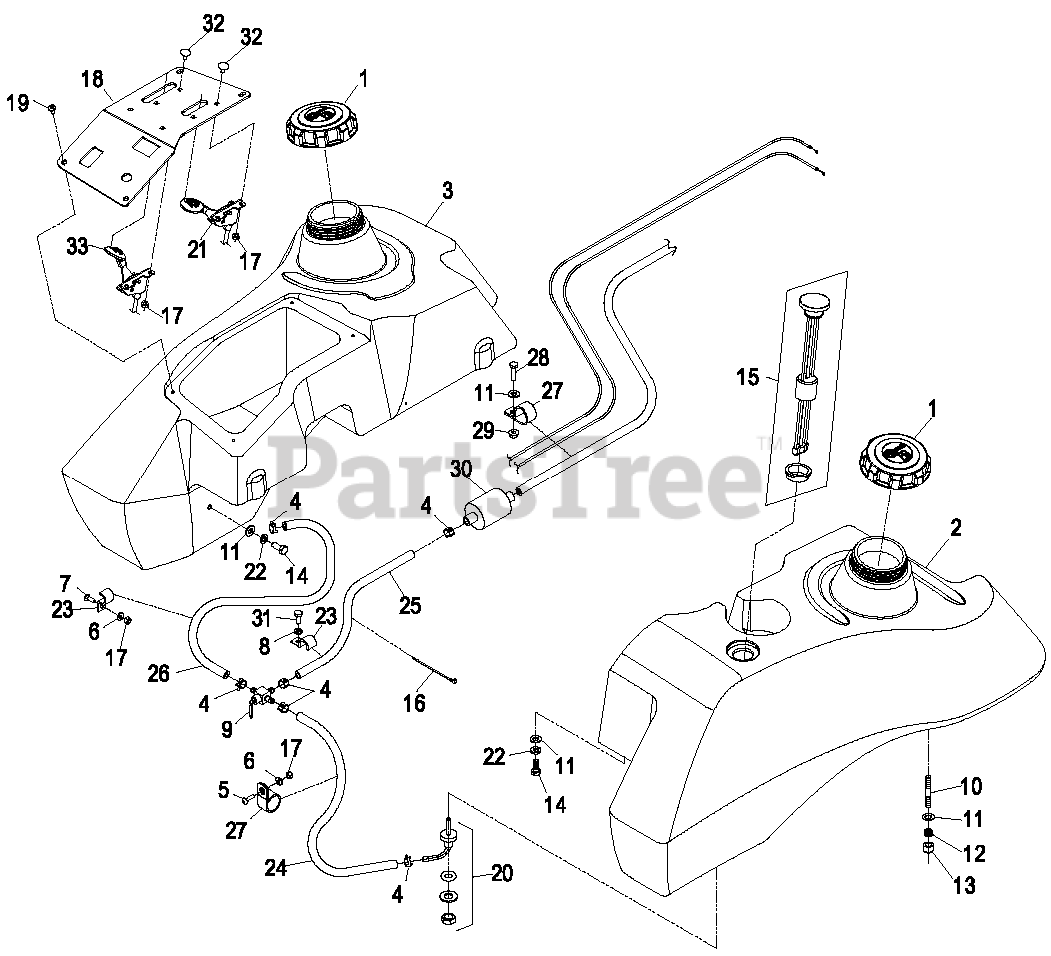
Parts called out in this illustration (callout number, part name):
1	CAP-FUEL, GAS
2	KIT,FUEL TANK LH LZXS
3	KIT,FUEL TANK RH LZXS
5	SCREW-HEAD, TRUSS
6	WASHER-FLAT
7	BOLT-CARR
8	WASHER-LOCK
9	VALVE-FUEL
10	STUD
11	WASHER-PLAIN
12	SPRING-TANK, FUEL
13	NUT-LOCK, NI
14	SCREW-HH
15	KIT, CT FUEL GAGE REPL.
16	TIE-PLASTIC
17	NUT-LOCK, NI
18	PANEL,CONTROL W/DECALS
19	SCREW-PPH
20	FITTING-FUEL, BULKHEAD
21	CONTROL-THROTTLE
22	WASHER-LOCK
23	CLIP-HALF, LOOM
24	HOSE-FUEL
26	HOSE-FUEL
27	CLIP-LOOM
28	SCREW-HH
30	P/N 695327 Fuel Filter
31	SCREW-HH
32	BOLT-CARR
33	CONTROL,CHOKE
